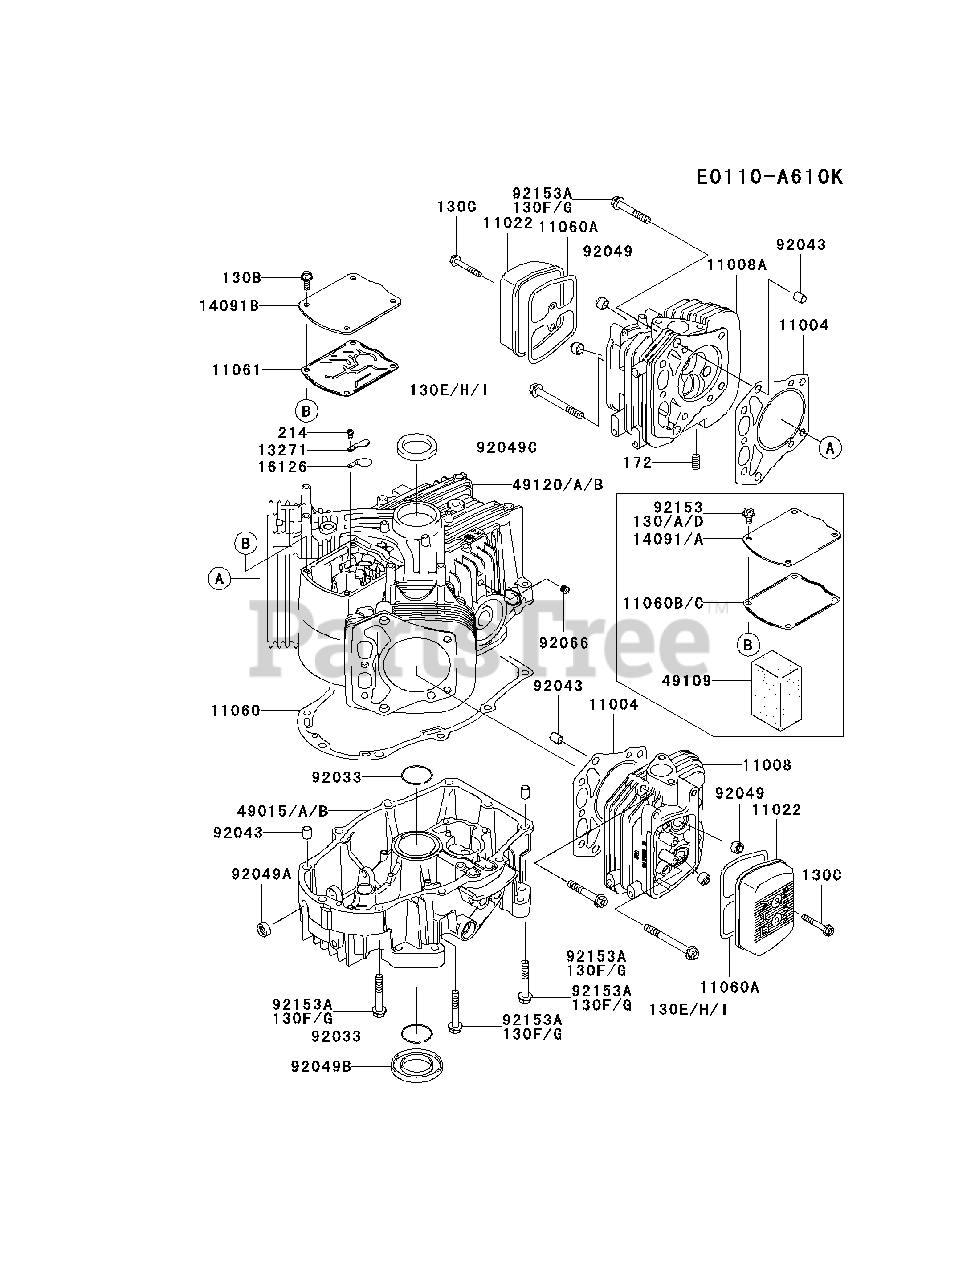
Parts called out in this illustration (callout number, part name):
130C	BOLT-FLANGED,6X40
130D	BOLT-FLANGED,6X12
130E	BOLT-FLANGED,8X75
130G	BOLT-FLANGED,8X50
130I	BOLT-FLANGED,8X75
172	BOLT-STUD,8X18
214	SCREW-PAN+-,4X8
